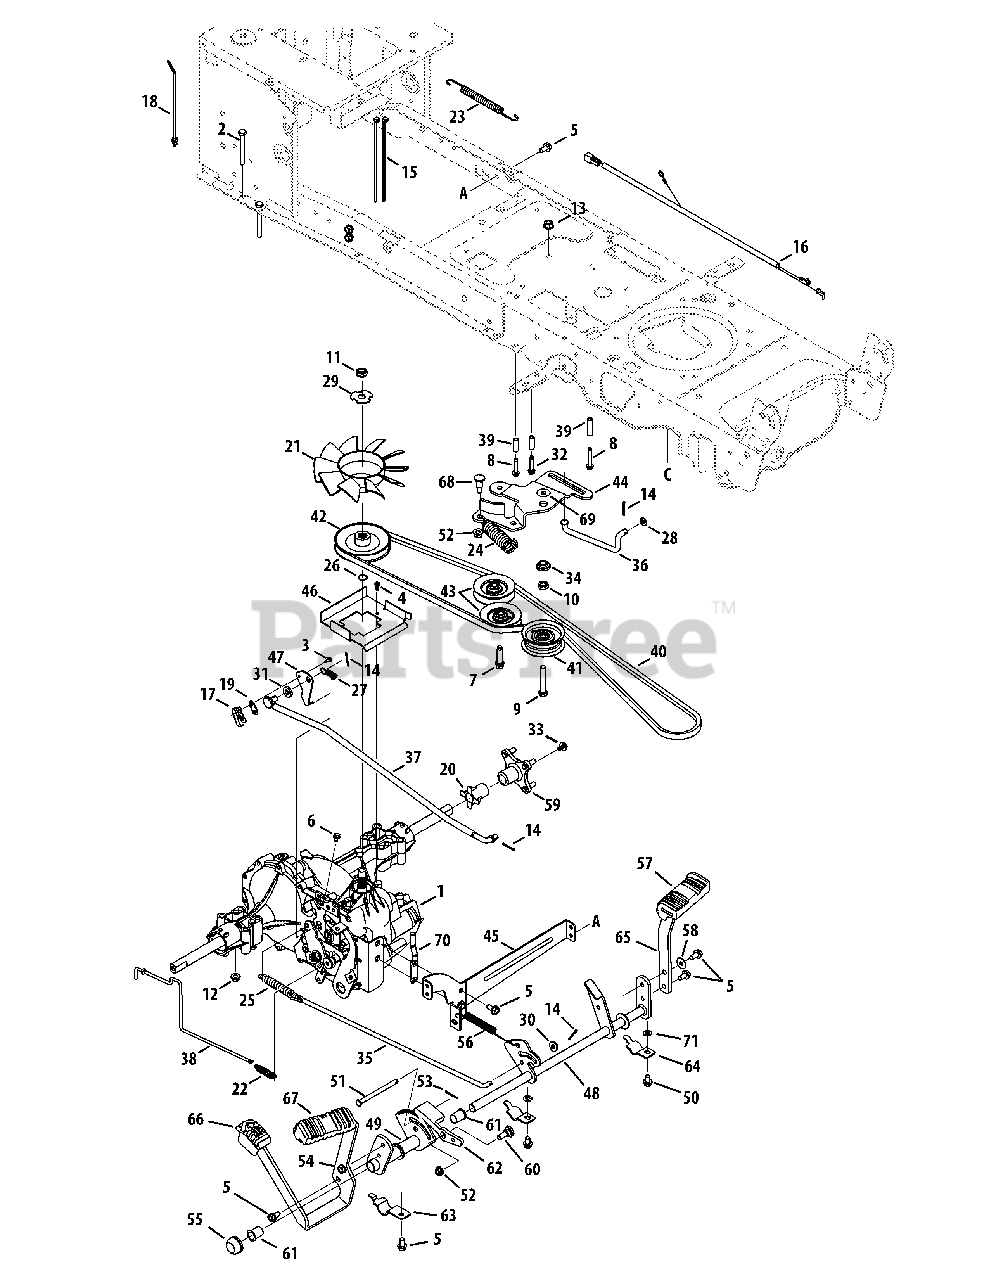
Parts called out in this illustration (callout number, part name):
1	Transmission, Hydro-Gear 0610
2	Hex Screw, 5/16-18, 2.75, Gr5, Std
3	Screw, #8-18, 0.500,
4	Screw, #10-16, 0.500
5	Screw, Self-tapping, 5/16-18, .750
6	Screw, Self-tapping, 1/4-20, 0.375
7	Screw, Self-tapping, 3/8-16, 1.500
8	Screw, Self-tapping, 1/4-20, 1.625
9	Hex Screw, 3/8-16, 2.25, Gr5
10	Nut, Jam, 7/16-20, Gr2
11	Nut, Jam Lock, 1/2-20, Gr5, Nylon
12	Nut, Flange Lock, 5/16-18, Nylon
13	Nut, Flange Lock, 3/8-16
14	Pin, Cotter, 3/32, 1.0
15	Cable, Tie, 3/16 x .05 x 7.4
16	Jumper Harness, Ground & Reverse
17	Switch, Spring, Short
18	Tie, Cable, Push Mount 7.5
19	Plate, Insulator Nut
20	Sleeve, .765 Id x 2.41
21	Fan, Hydro
22	Spring, Extension, .48 Od x 2.03
23	Spring, Extension, .500 Dia x 12.6
24	Spring, Extension, 1.00 Dia x 4.75
25	Spring, Extension, .59 Od x 4.00
26	Ring, Wire
27	Spring, Extension, .375 Od x 1.44
28	Washer, Flat, .330 x .630 x .0635
29	Washer, Lock, Transmission Hydro
30	Washer, Flat, .344 x .750 x .120
31	Washer, Flat, .407x.812x.135, Ht
32	Screw, Self-tapping, 1/4-20, 1.75
33	Screw, 5/16-24 x .750
34	Spacer, Shoulder, 1.375 x .380 x .183
35	Rod, Brake, LT Hydro
36	Rod, Transmission, Bypass
37	Rod, Control, Hydro
38	Rod, Hydro Bypass
39	Spacer, .260 x .372 x 1.420
40	Belt, V-Type
41	Pulley, Idler, Flat 2.75 OD
42	Pulley, Input, 4.13 Dia
43	Pulley, Idler, V-Type x 3.06
44	Bracket, Idler, Center Double
45	Bracket, Mount, Hydro
46	Bracket, Support, Belt Disengage
47	Bracket, Actuator, Switch
48	Control Assembly, Brake
49	Bracket Assembly, Pedal, Hydro
50	Screw, Self-tapping, 5/16-18, 0.625,
51	Pin, Clevis, 5/16 x 3.985
52	Nut, Flange Lock, 3/8-16, Nylon
53	Pin, Cotter, Bow-Tie 72
54	Bracket, Pedal, Hydro
55	Cap, Push 5/8
56	Spring, Extension, .63 Dia x 4.95
57	Pad, Pedal, Brake
58	Washer, Bell, .340 x .872 x .060
59	Hub Assembly, Wheel
60	Bolt, Shoulder, .500 x .270, 3/8-16
61	Bearing, Flange, .630 x .695 x .60
62	Latch, Cruise
63	Bracket, Support, Pedal Strap
64	Bracket, Support, Pedal Strap 5/8
65	Bracket, Pedal, Brake
66	Pad, Pedal, Reverse
67	Pad, Pedal, Forward
68	Scr, Shldr, .50 x .685 3/8-16
69	Washer, Flat, .385 x 1.0 x .030
70	Belt Keeper Rod
71	Flat Washer, .344 x .688 x .065
